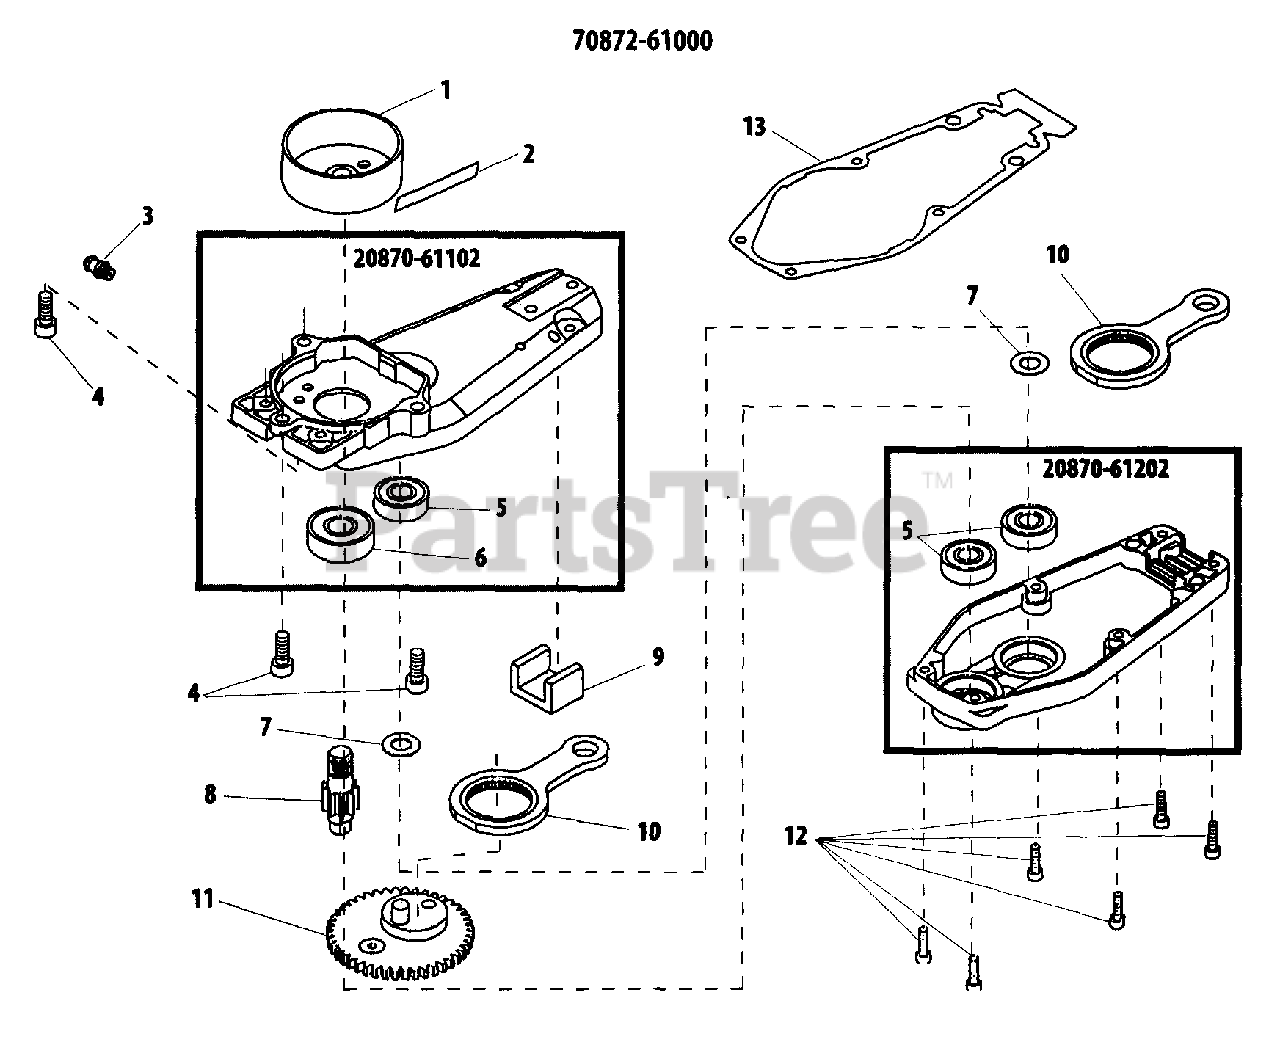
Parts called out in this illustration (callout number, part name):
1	DRUM, CLUTCH
2	LABEL, LUBE BLADES
3	FITTING, GREASE
4	BOLT 6×16
5	BEARING, BALL 6000ZZ
6	BEARING, BALL 6201
7	WASHER, THRUST
8	GEAR, SHAFT
9	SEAL, FELT
10	CONNECTING ROD ASSY
11	GEAR
12	BOLT 4×14
13	GASKET, GEAR CASE
20870-61102	GEAR CASE ASSY - UPPER
20870-61202	CASE COVER COMPLETE
70872-61000	GEAR CASE ASSY
